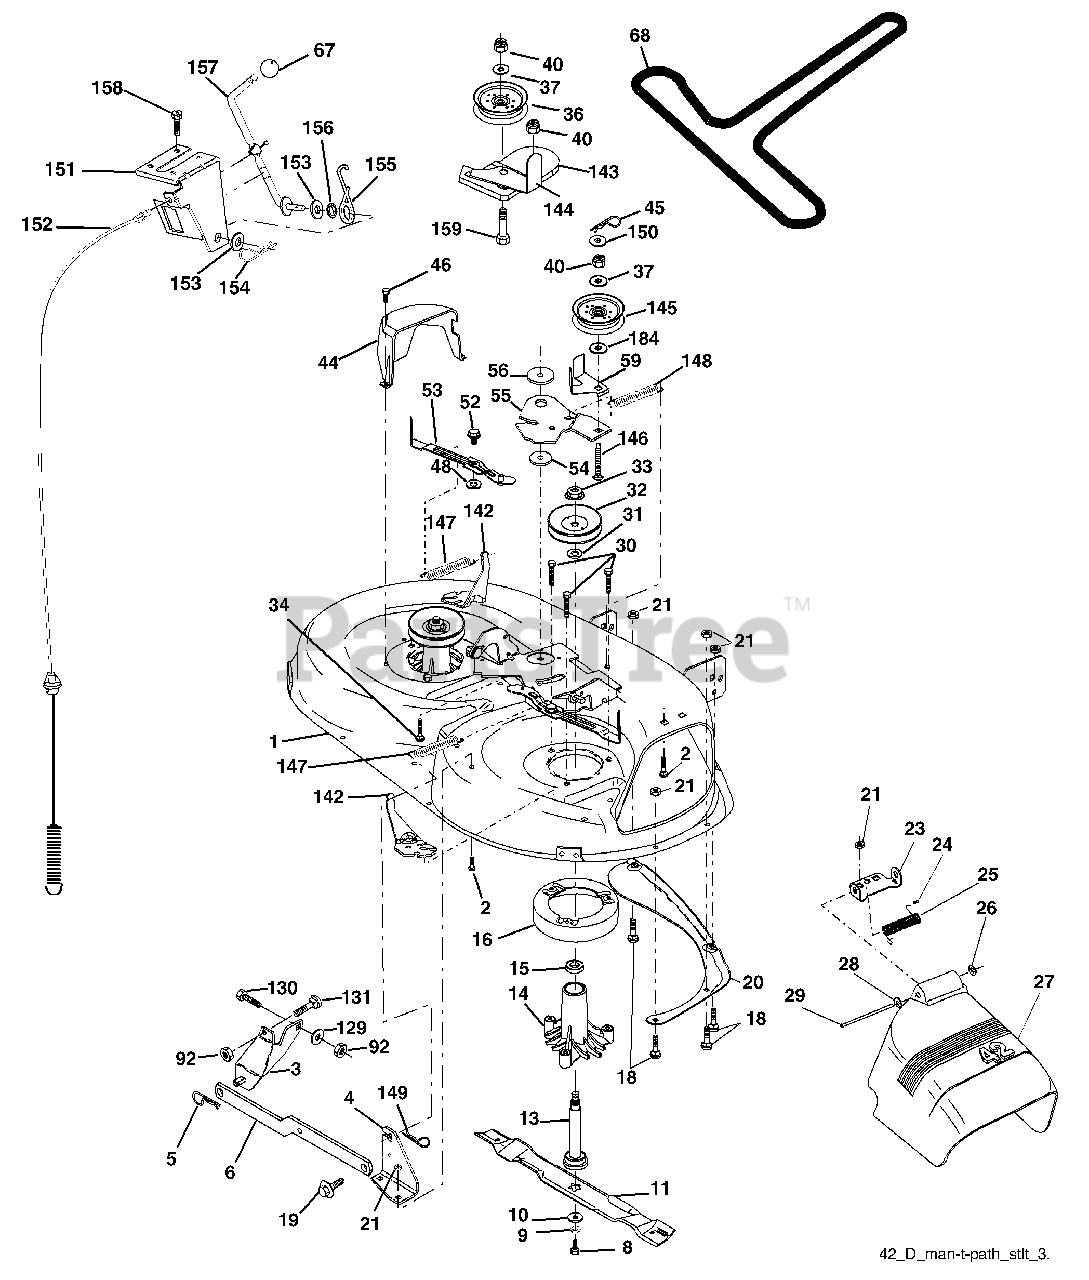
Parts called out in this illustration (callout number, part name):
1	Mower Deck Assembly, 42"
2	Bolt
3	Bracket Asm Fr. Sway Bar 3/42
4	Bracket Asm Deck 42" Sway Bar
5	Retainer Spring
6	Bar Sway Deck
8	Bolt 3/8-24 x 25 Grade 8 patched
9	Washer, Lock
10	Washer, Hardened
11	Blade, 42" Mulching Std
11	Blade, 42" Mulching Premium
11	Blade, 42" Hi-Lift
13	Shaft Assembly, Mandrel, Vented
14	Housing, Mandrel, Vented
15	Bearing, Ball, Mandrel
16	Stripper, Mandrel Deck
18	Bolt, Carriage 5/16-18 x 5/8
19	Bolt, Shoulder
20	Baffle, Vortex
21	Nut
23	Bracket,Deflector Mower 42"
24	Cap, Sleeve 80 x 112 Blk Mower
25	Spring, Torsion, Deflector 2 52
26	Nut, Push Phos & Oil
27	Shield, Deflector 42" Blk
28	Washer 11/32 x 5/8 x 16 Gauge
29	Rod, Hinge 42" 6 75 W/G
30	Screw Thdrol Washer Head
31	Washer, Spacer Mower Vented
32	Pulley, Mandrel
33	Nut, Toplock 9/16 Flange
34	Bolt
36	Pulley, Idler, Flat
37	Washer 13/32 x 13/16 x 16 Gauge
40	Nut
44	Guard, Mandrel, LH
45	Retainer
46	Screw, Thdrol 1/4-20 x 5/8 T
48	Washer, Hardened
52	Bolt, Shoulder 5/16-18 UNC
53	Arm Assembly, Pad, Brake
54	Washer, Hardened
55	Arm, Idler
56	Spacer, Retainer
59	Guard TUV Idler
67	Knob
68	V-Belt, 42" Mower
142	Arm Spring Brake Mower
143	Bracket Arm Idler 42"
144	Keeper Belt 42" Clutch Cable
145	Pulley Idler Flat
146	Bolt Carriage Idler
147	Spring Extension
148	Spring Return Idler
149	Retainer Spring Yellow
150	Washer 9/32 x 3/4 x 16 Ga.
151	Bracket Clutch Cable
152	Clutch Cable 42"
153	Washer Flat 3/8" Type B
154	Spring Retainer
155	Spring Retention LVR CLTCH CAB
156	Spacer Clutch Cable
157	Rod Clutch Cable 3/8"
158	Screw Hex Thd Cut 1/4-20 x 1/2
159	Bolt Rdhd Sqn 3/8-16 UNC x 1-3/4
184	Washer 13/32 x 7/8 x 10 Ga.
